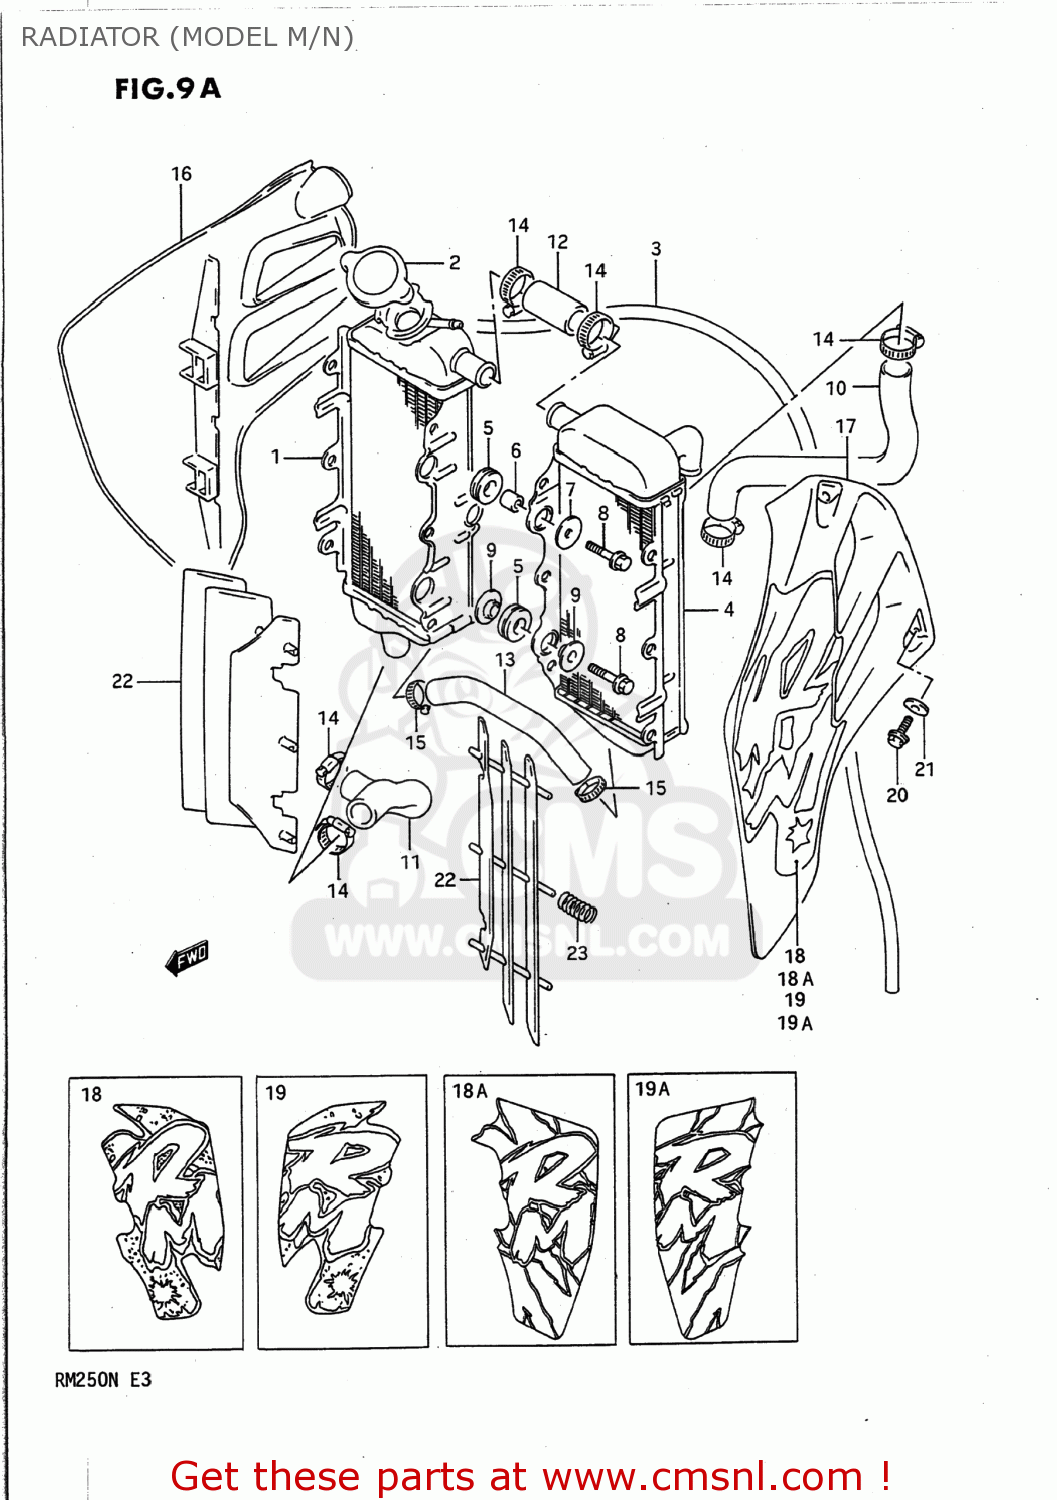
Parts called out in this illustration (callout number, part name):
1	RADIATOR,WATER,R
2	CAP,RADIATOR 1.1
3	HOSE
4	RADIATOR,WATER,L
5	CUSHION,RADIATOR LWR
6	SPACER(6.5X10.5X12)
7	WASHER (6.5X24X1.2)
8	BOLT
9	WASHER,RDTR SPRT
10	HOSE,RADIATOR INLET
11	HOSE,RADIATOR OUTLET
12	HOSE,RADIATOR JOINT NO.1
13	HOSE,RADIATOR JOINT NO.2
14	CLAMP
15	CLAMP
16	COVER,RADIATOR,RIGHT
17	COVER,RADIATOR,LEFT
18	EMBLEM,RADIATOR COVER
18A	EMBLEM,RADIATOR COVER
19	EMBLEM,RADIATOR COVER
19A	EMBLEM,RADIATOR COVER
20	BOLT
21	GASKET(6.5X20X1.5) (NAS)
22	LOUVER,RADIATOR
23	SPRING
